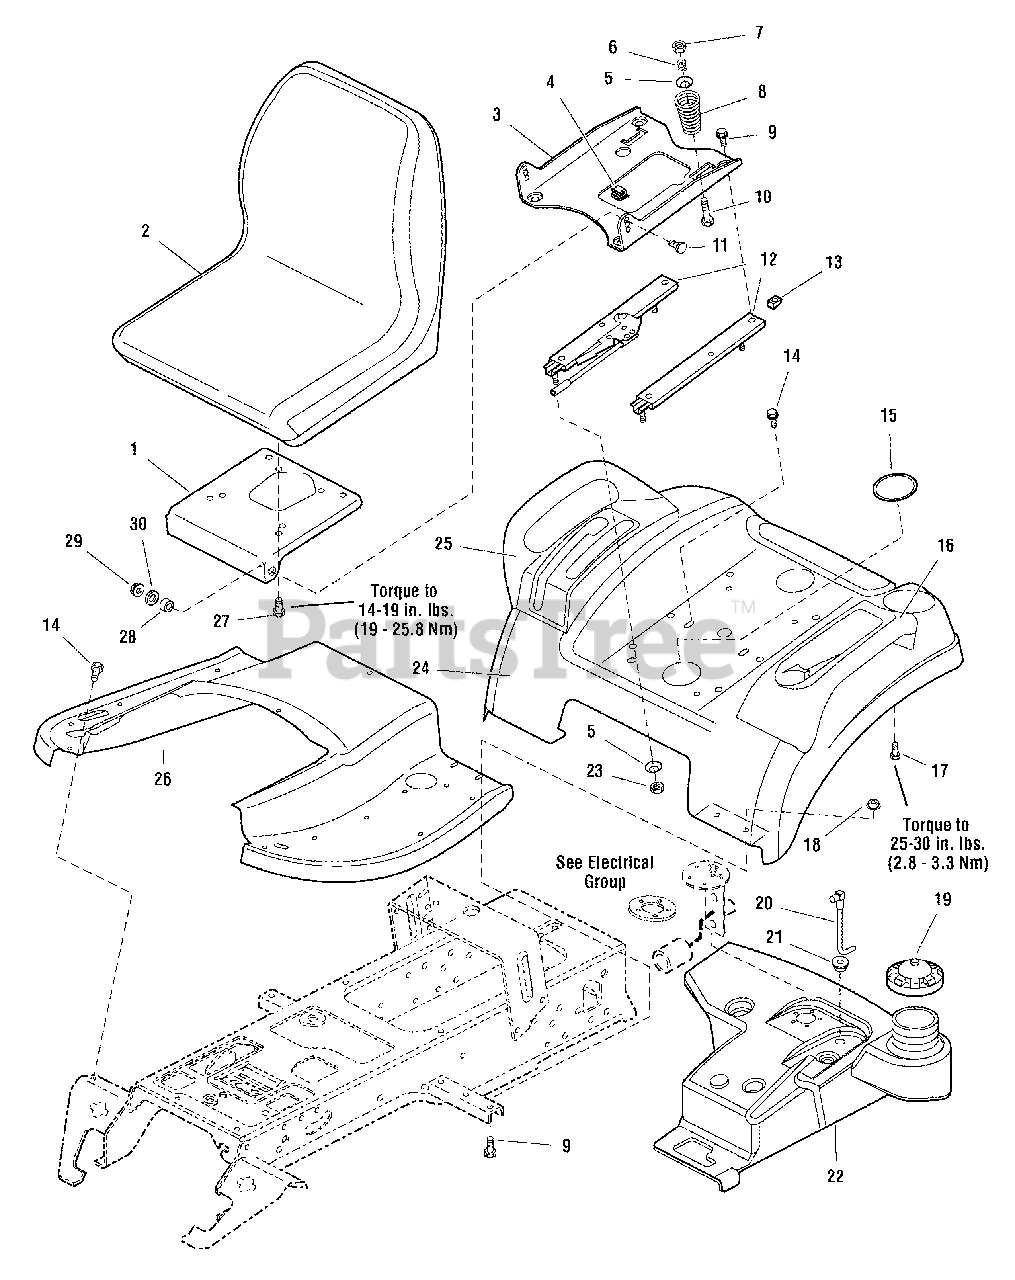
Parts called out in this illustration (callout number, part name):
1	BRACKET, 1-5/8 x 1-3/4
2	SEAT, 15" Back
3	SUPPORT, Seat
4	CLIP, Wire
5	WASHER, Spring, 5/16 x 1-1/4
6	SPRING, Compression
7	NUT, Hex Lock ESNA Light, 5/16-18
8	SPRING, Compression
9	CAPSCREW, Hex Flange Whiz Lock, 5/16-18 x 3/4
10	CARRIAGE BOLT, 5/16-18 x 2
11	CARRIAGE BOLT, 3/8-16 x 1
12	SLIDE, Seat
13	NUT, Speed, Lug Type, 5/16-18
14	CAPSCREW, Hex Washer Head Taptite, 5/16-18 x 5/8
15	PLUG, Plastic
16	POD, with Cup Holder, LH
17	CAPSCREW, Hex Washer Head, 1/4-20 x 5/8
18	NUT, Hex Flange Whiz Lock, 5/16-18
19	CAP, Gas
20	TUBE & ELBOW ASSEMBLY
21	BUSHING, 3/8 x 9/16 x 5/8, Rubber
22	TANK, Fuel
23	NUT, Hex KEPS, 5/16-18
24	DECK, Seat, Red
25	POD, RH with 2 Slots
26	TUNNEL, Red
27	CAPSCREW, Hex Flange Whiz Lock Dog Point, 5/16-18 x 1
28	SPACER, 25/64 x 5/8 x 3/16, Hardened
29	NUT, Hex Flange Two-Way Lock, 3/8-16
30	WASHER, 3/8
